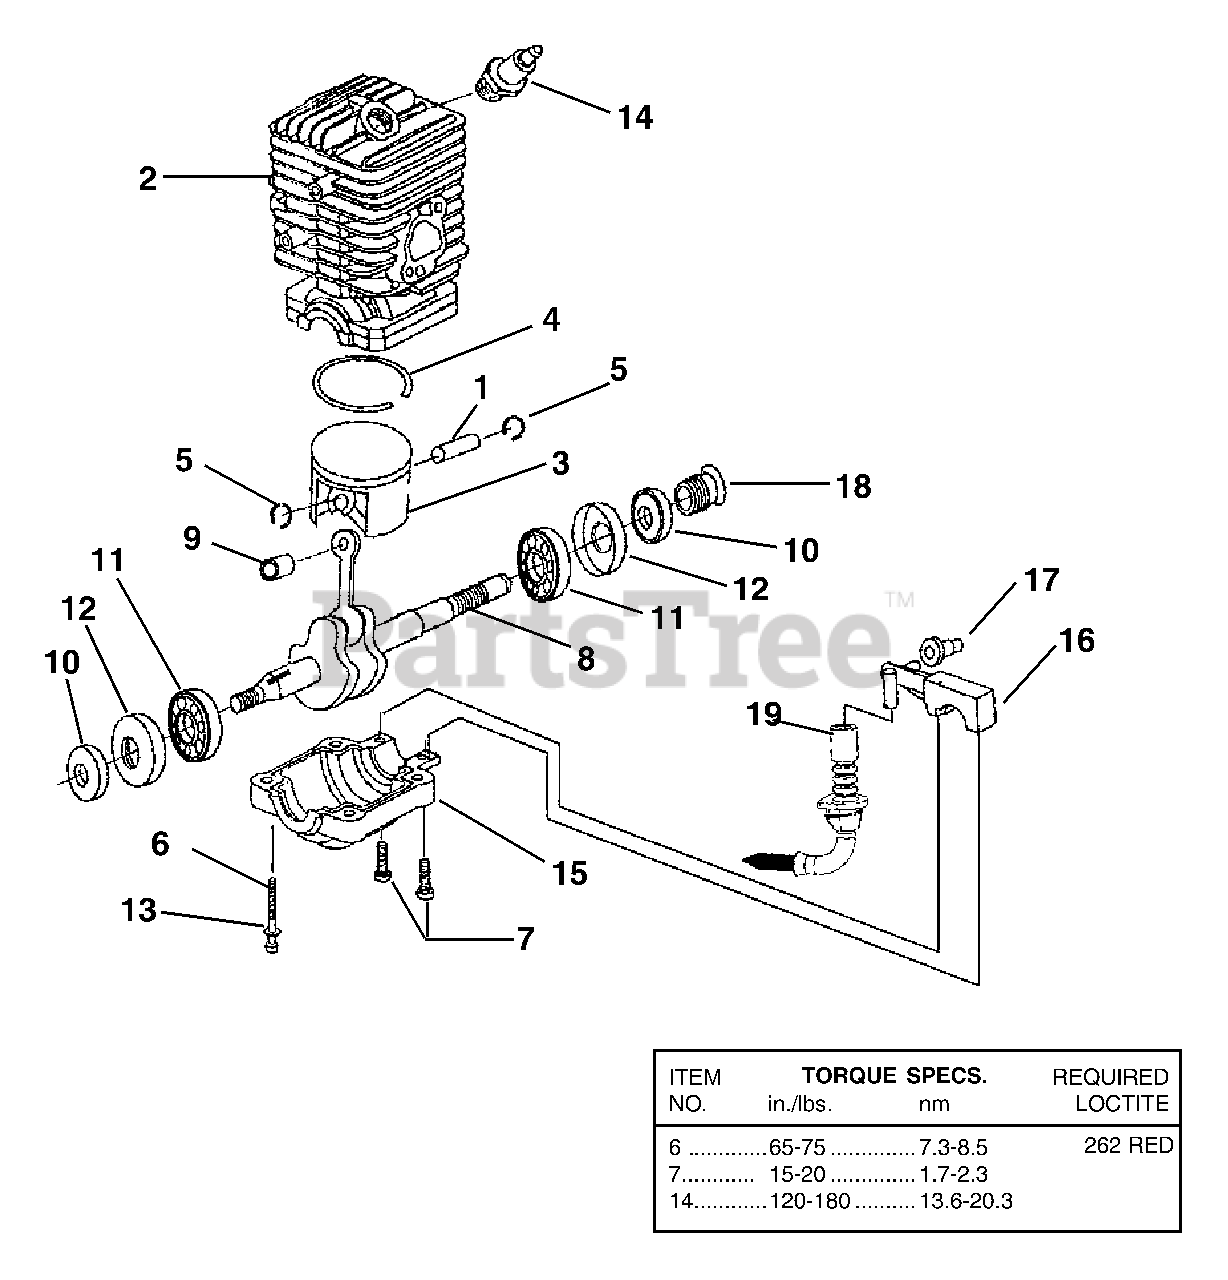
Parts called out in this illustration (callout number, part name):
1	PISTON PIN
2	CYLINDER MACH/PLATED
3	33CC PISTON (MACH)
4	PISTON RING
5	RETAINING RING
6	SCREW TORX PLUS CAP-SOCKET HD
7	SCREW, (8/32 X 5/8 in. PAN HD .TORX)
8	33 CC CRANKSHAFT ASSEMBLY
9	NEEDLE BEARING
10	SHAFT SEAL
11	BALL BEARING
12	BEARING CASE
13	FLAT WASHER
14	SPARK PLUG
15	CRANKCASE (33CC) CS
16	OIL PUMP ASSEMBLY
17	GROMMET, OIL OUTLET
18	LEFT HAND WORM
19	OIL INTAKE TUBE W/FILTER
